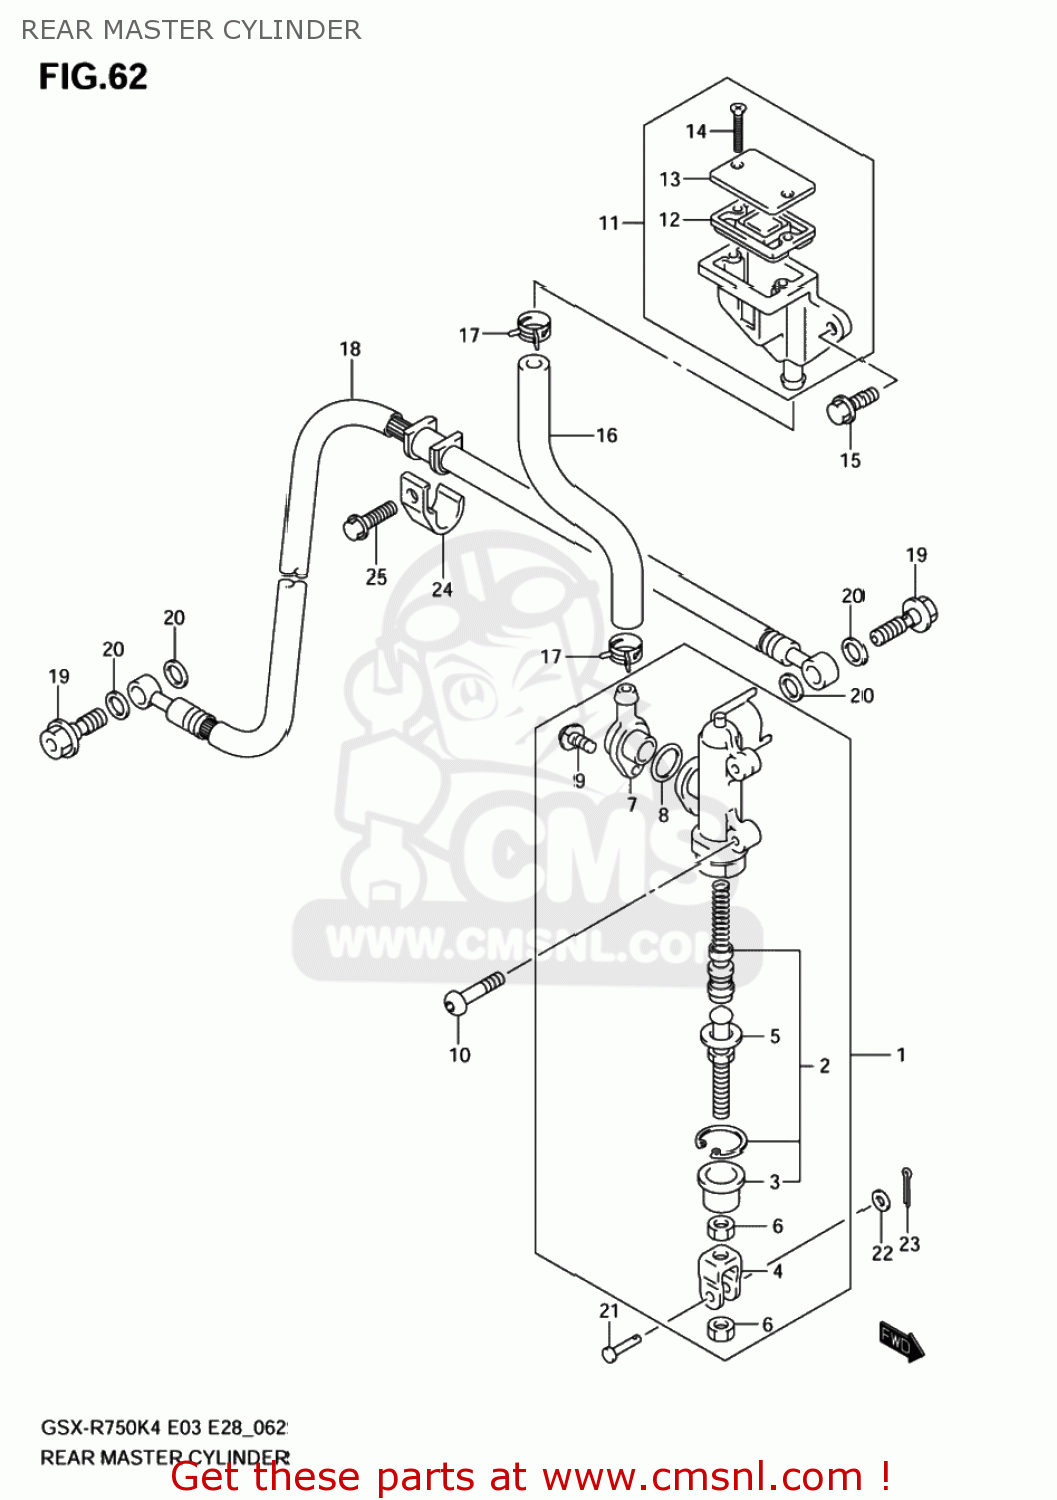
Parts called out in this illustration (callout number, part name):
1	CYLINDER ASSY,RR MASTER
2	PISTON/CUP SET
3	BOOT
4	YOKE
5	ROD,PUSH
6	NUT
7	CONNECTOR
8	O RING
9	SCREW
10	SCREW(6X20)
11	TANK ASSY,RR RESERVOIR
12	DIAPHRAGM
13	CAP
14	SCREW
15	BOLT(6X12)
16	HOSE,RR RESERVOIR TANK
17	CLIP
18	HOSE, REAR BRAKE
19	BOLT UNION
20	WASHER(10X15X1.5)
21	PIN
22	WASHER
23	PIN
24	CLAMP,RR BRAKE
25	BOLT(6X20)
